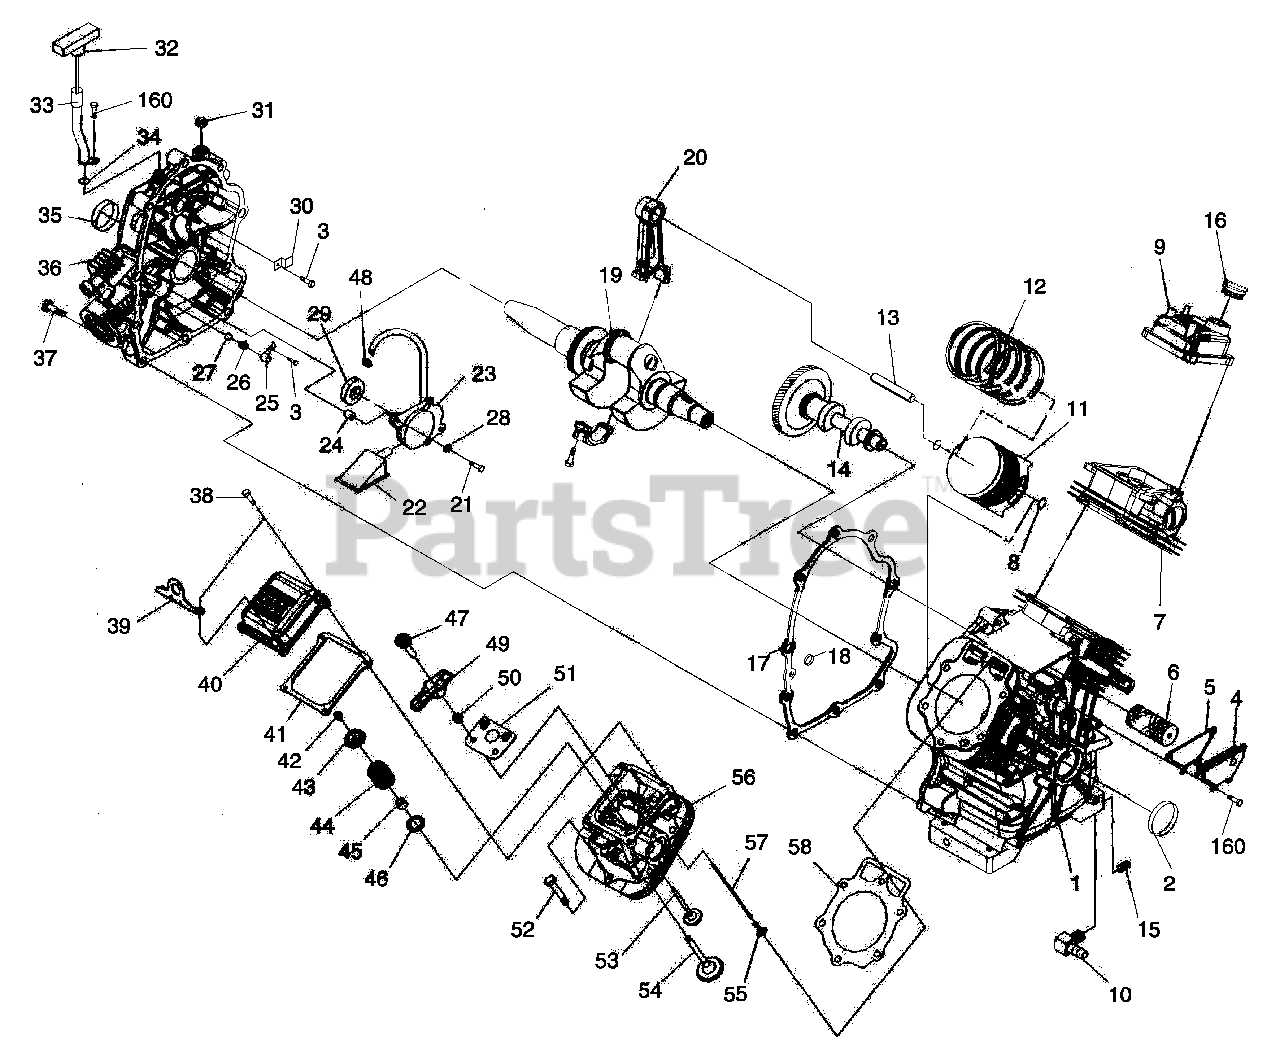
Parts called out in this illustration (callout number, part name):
1	ASSEMBLY, CRANKCASE HOUSING WITH SLEEVE
2	SEAL, 38 I.D. CRANKSHAFT
3	SCREW, TAPTITE M6-1.0 X 12 BP
4	ASSEMBLY, BREATHER
5	GASKET, BREATHER COVER
6	SEPARATOR, OIL BREATHER
7	ASSEMBLY, HEAD #1
8	RETAINER, PISTON PIN 20
9	ROCKER, COVER
10	BARBED EL 90 3/8NPT X 3/8
11	PISTON, LC (GT-990)
12	SET, PISTON RING 90MM
13	PIN PISTON
14	ASSEMBLY, CAMSHAFT & GEAR
15	PLUG STD PIPE 3/8 STEEL SO HD
16	ASSEMBLY, OIL FILL CAP
17	GASKET, CRANK CASE
18	SEAL, OIL PASSAGE
19	ASSEMBLY, CRANKSHAFT HORIZONTAL DIRECT DRIVE (GT-990)
20	ASSEMBLY, CONNECTING ROD (GT-990)
21	SCREW SHC M6-1.0 X 50 G8.8
22	SCREEN, OIL PICKUP
23	ASSEMBLY, OIL PUMP
24	SLEEVE, SEAMED DOWEL 10 DIA.
25	COVER, OIL RELIEF
26	SPRING, OIL RELIEF
27	BALL, 1/2D OIL RELIEF
28	WASHER, LOCK RIB M6
29	GEROTOR, OUTER
30	CLAMP, OIL TUBE
31	PLUG-CRANKCASE GOVERNOR BORE
32	ASSEMBLY, DIPSTICK WITH HANDLE
33	TUBE, DIPSTICK
34	O-RING, OIL CLR
35	SEAL, 42 I.D. CRANKSHAFT
36	ASSEMBLY, HOUSING COVER WITH SLEEVE
37	SCREW, HHFC M10-1.5 X 55
38	SCREW HHFC M6-1.0X25
39	HOOK, LIFTING
40	ROCKER, COVER
41	GASKET, VALVE COVER
42	KEEPER, VALVE SPRING
43	RETAINER, VALVE SPRING
44	SPRING, VALVE
45	SEAL, VALVE STEM D7
46	WASHER, VALVE SPRING
47	STUD, ROCKER ARM PIVOT
48	O-RING, 3/8" X 1/2"
49	ROCKER ARM
50	NUT, HEX M8-1.0 GB YELLOW CHROME
51	PLATE, PUSH ROD GUIDE
52	SCREW HHFC M8-1.25 X 65
53	VALVE, EXHAUST
54	VALVE, INTAKE
55	TAPPET, SOLID
56	ASSEMBLY, HEAD #2
57	PUSHROD 147
58	GASKET, HEAD
59	KIT GEAR COVER
60	KIT GASKET
61	KIT PISTON & RINGS
62	KIT BREATHER ASSEMBLY
63	KIT HEAD ASSEMBLY CYL 1
64	KIT HEAD ASSEMBLY CYL 2
65	KIT OIL RELIEF
